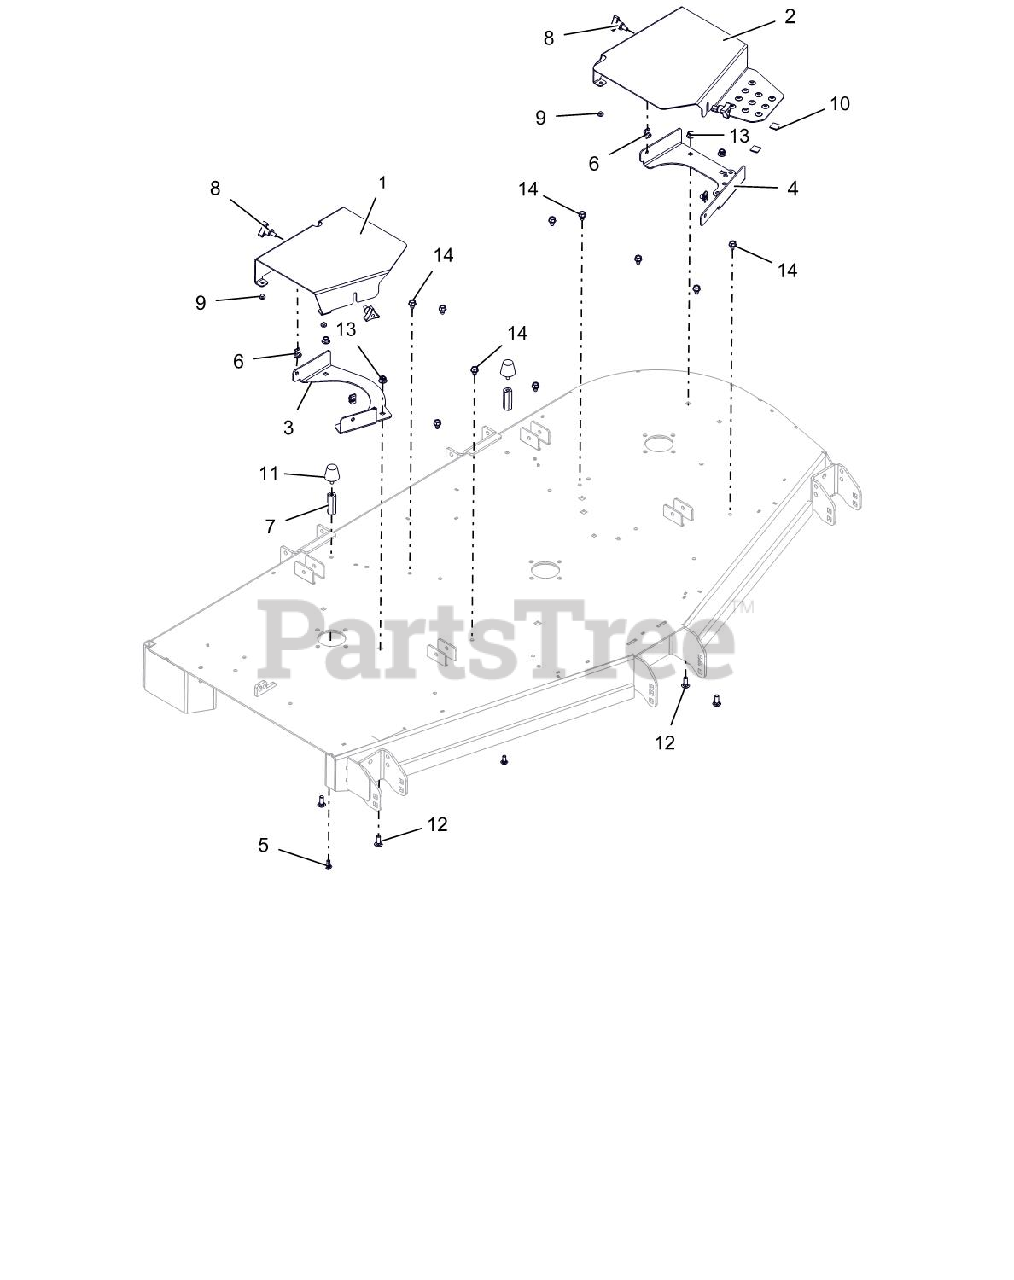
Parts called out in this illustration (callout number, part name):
1	GUARD, RH DECK - RED
2	GUARD, LH BELT - RED
3	BRKT, RH BELT GUARD MTG - RED
4	BRKT, LH BELT GUARD MTG - RED
5	BLT,RDHDSQNK .31-18X.75 LOCTIT
6	NUT-CLIP RETAINER 5/16-18X.56
7	NUT, .31-18X2.25 LG COUPLING
8	KNOB,WING STUD 5/16-18 X .75
9	BUMPER GROMMET
11	BUMPER, RUBBER CONE,STUD MOUNT
12	@BLT-RDHDSQNK .38-16X1.00 G5YZ
13	@NUT-LK-NYL-FLG .38-16 YWZC
14	@SCR-TAP .38-16X.50 HWH TR YWZ
